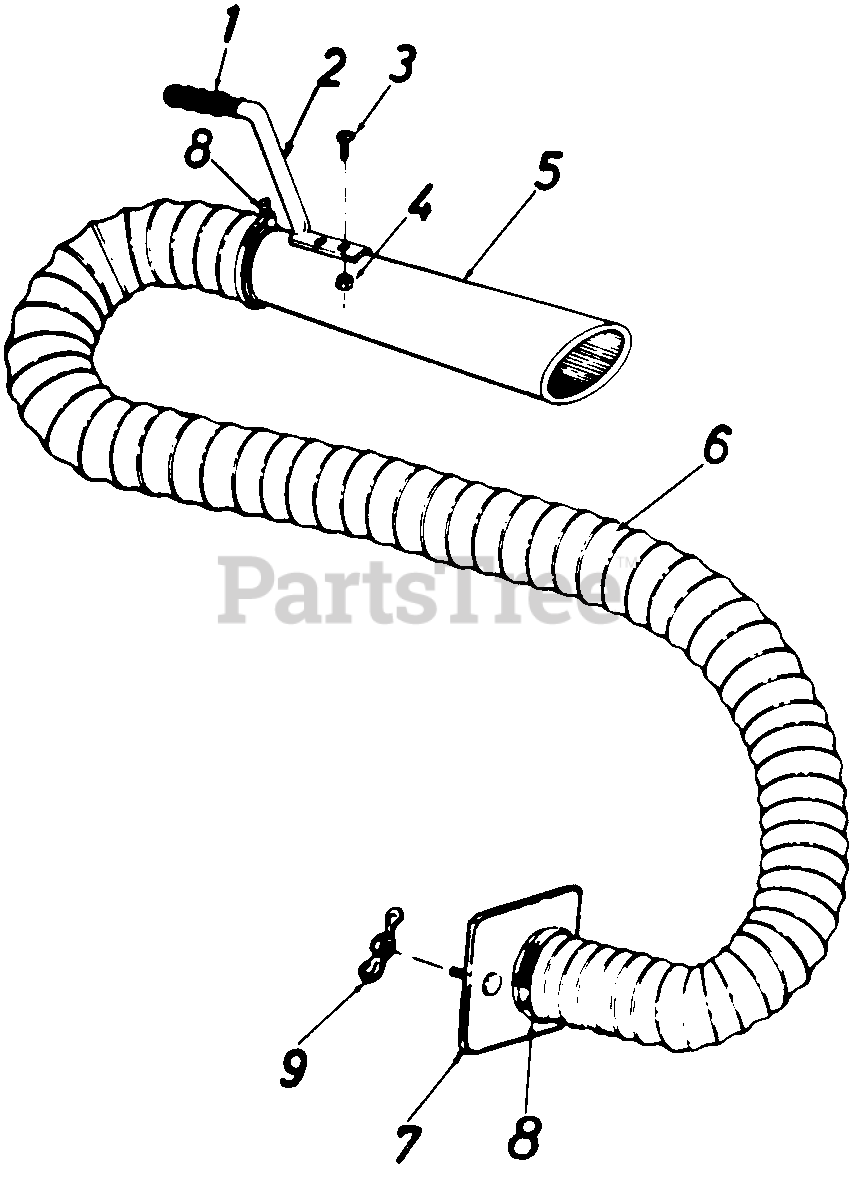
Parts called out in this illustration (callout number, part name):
1	Handle Grip
2	Handle
3	Truss Sems Scr. 10-24 x 1/2" Lg.
4	Hex Nut 10-24 Thd.
5	Hose Nozzle
6	Flexible Hose 4" Dia. x 10" Lg.
7	Hose Adapter Plate
8	Hose Clamp - For 4" Dia. Hose
9	Wing Nut 1/4-20 Thd.
